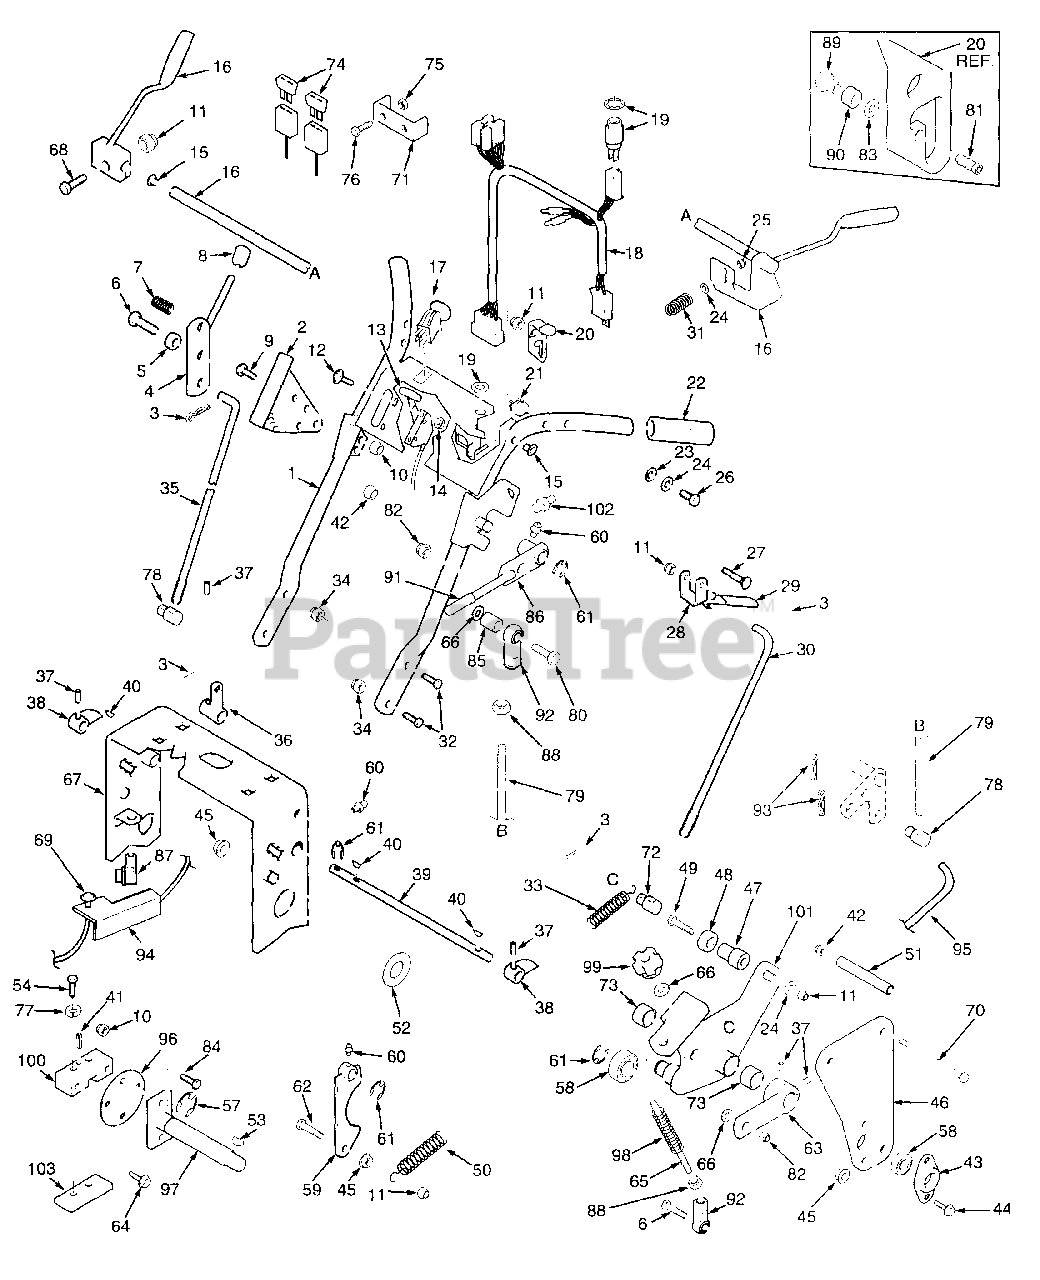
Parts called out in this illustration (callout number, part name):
1	Upper Handle Wlmt. W/Decals
2	Quadrant, Speed Control
3	Hairpin, .094 x 1.19
4	Lever, Speed Adjustment
5	Bushing, Speed Adjustment Lever
7	Ball Plunger
8	Knob, Speed Adjustment
9	Capscrew, 1/4-20 x 3/4" FHHS
10	Nut, 1/4-20 Elastic Stop
11	Nut, 5/16-18 Elastic Stop
12	Screw, #10-32 x 1/2" PW HD
13	Throttle Control
14	Nut, #10-32 Serr. Flange
15	Bushing
16	Handle, Oper. Presence-RH
17	Switch, Elec. Clutch Eng.
18	Wire Harness, Manual Start
19	Key Switch, Manual Srt.
20	Neutral Latch-RH
21	Switch, Neutral Interlock
22	Grip
23	Washer, Curved Spring
24	Flat Washer
25	Nut, 5/16-18 Elastic Stop
28	Lever, Steering Control
29	Grip, Steering Control
30	Rod, Steering Control
31	Spring, Handle Return
32	Capscr., 3/8-16 x 1" Ser. Flange
33	Spring
34	Nut, 3/8-16 Serr. Flange
35	Rod Speed Control
36	Bellcrank, Speed Control
38	Cam, Speed Control
39	Jackshaft, Speed Control
40	Key, 1/8 x 1/2" Woodruff
43	Flange, Bearing
44	Capscrew, 5/16-18 x 1" Serr. Flg.
45	Nut, 5/16-18 Serrated Flange
46	Plate, Side
47	Support, Neutral Support
48	Bearing, Speed Ctrl. Bellcrank
50	Spring, Return
51	Spacer, Side Plate
52	Flat Wshr., 3/4-.766 x 1.25 x .035
53	Key, Woodruff, 3/16 x .75"
54	Bolt, Hex Head, 1/4-20 x 1.25
57	Clip, Retaining .750 diameter
58	Bearing, Ball Neutral Return
59	Cam, Neutral
60	Grease Fitting, 1/4-28 UNF
61	Retaining Ring, 5/8 Ext. "E"
63	Lever, Speed Control
65	Stud, 3/8-16x4.5
66	Flat Wshr., 15/16 x .3906 x 12 ga
67	Deck, Engine By Ref.
68	Hex Head Bolt, 5/16-18 x 1.25"
69	Choke Control
70	Bolt, Hex Head 3/8-16 x 4.25"
71	Fuse Holder
72	Swivel Joint, Steering Rod
73	Bushing
74	Blade Fuse, 20A
75	Nut, #10-32 Elastic Stop
76	Screw, #10-32 x 1.5" Phillips
77	Lockwasher, 1/4"
78	Swivel Joint
79	Rod, Brake Lever
80	Hex Hd. Bolt, 3/8-16 x 1.75"
82	Nut, 3/8-16 Elastic Stop
83	Washer #8-.170 x .375 x .032
85	Spacer
86	Parking Brake Lever with Grip
87	Switch, Safety
88	Nut, 3/8-24
89	Bushing, bearing Retainer
90	Bearing, Neutral Lock
91	Grip, Parking Brake
92	Ball Joint, RH Thread
93	Hairpin, .094 x 1.62"
94	Bracket, Choke Mtg.
95	Rod, Lower Brake
96	Plate, Coupler
97	Shaft, Pump Control
98	Spring
99	Knob, Tracking Adjustment
100	Block, Pump Control
101	Control, LH
102	Switch, Parking Brake
103	Plate, Threaded
